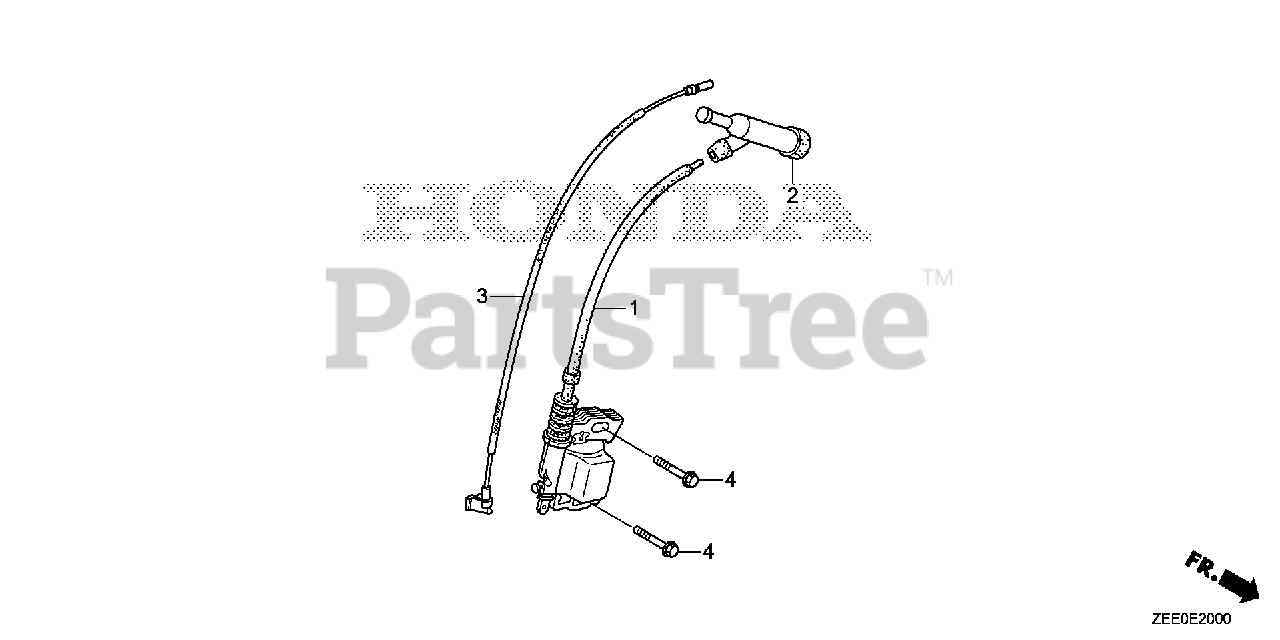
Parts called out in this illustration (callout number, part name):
1	COIL ASSY., IGNITION
1	COIL ASSY., IGNITION (KOKUSAN)
2	CAP ASSY., NOISE SUPPRESSOR (KOKUSAN)
3	WIRE, STOP SWITCH (370MM) (KOKUSAN)
3	WIRE, STOP SWITCH (370MM)
4	BOLT, FLANGE (6X25) Use up to Engine SN 2056819.
